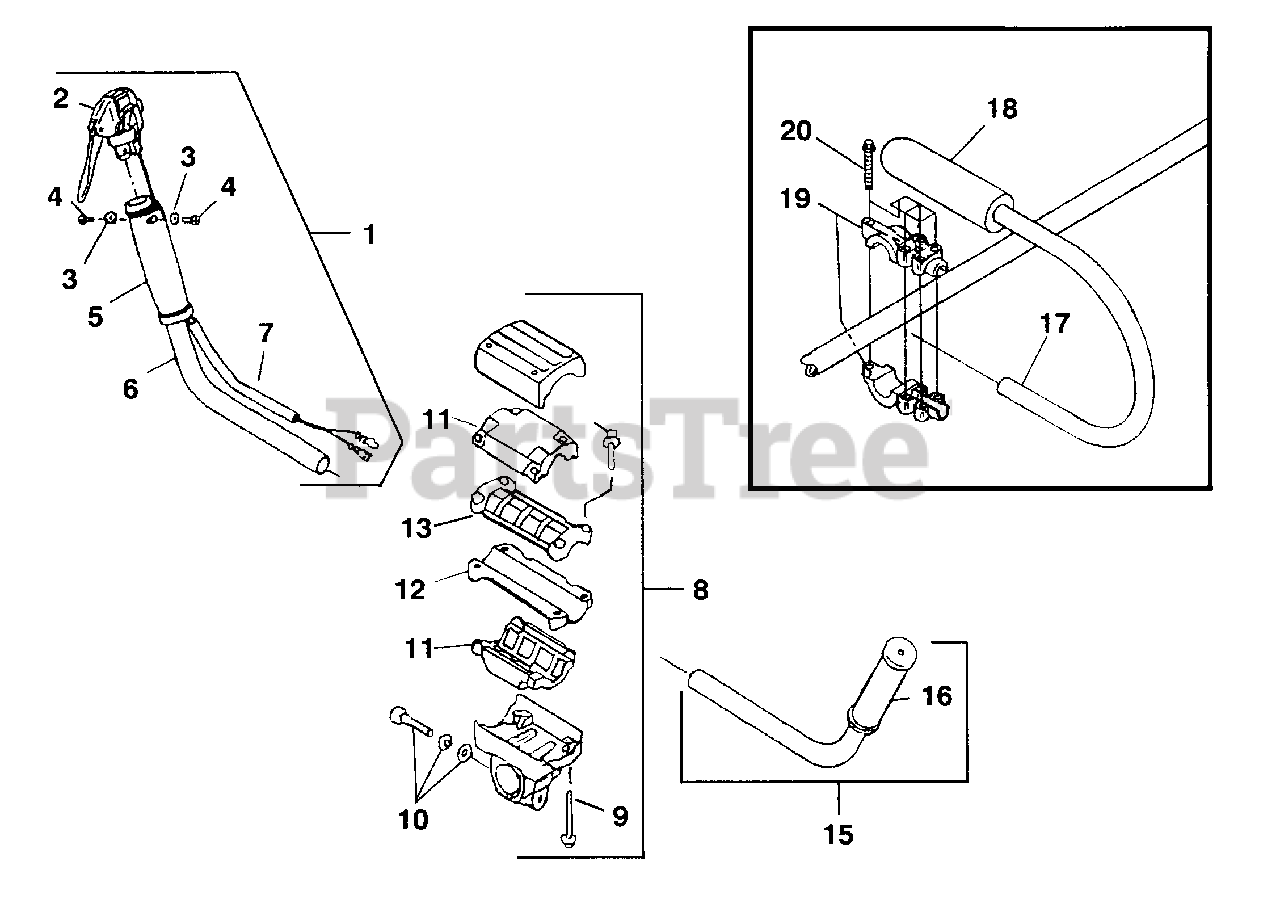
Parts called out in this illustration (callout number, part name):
1	HANDLE ASSY R.H.
2	THROTTLE SWITCH ASSY
3	WASHER
4	SCREW
5	GRIP R.H.
6	HANDLE
7	TUBE/WIRE HARNESS
8	HANDLE JOINT ASSY
9	BOLT
10	SCREW & WASHERS
11	ISOLATING RUBBER
12	PIPE FITTING
13	PIPE FITTING
14	BOLT
15	HANDLE ASSY L.H.
16	GRIP L.H.
17	HANDLE ASSY
18	GRIP
19	BRACKET ASSY
20	BOLT
